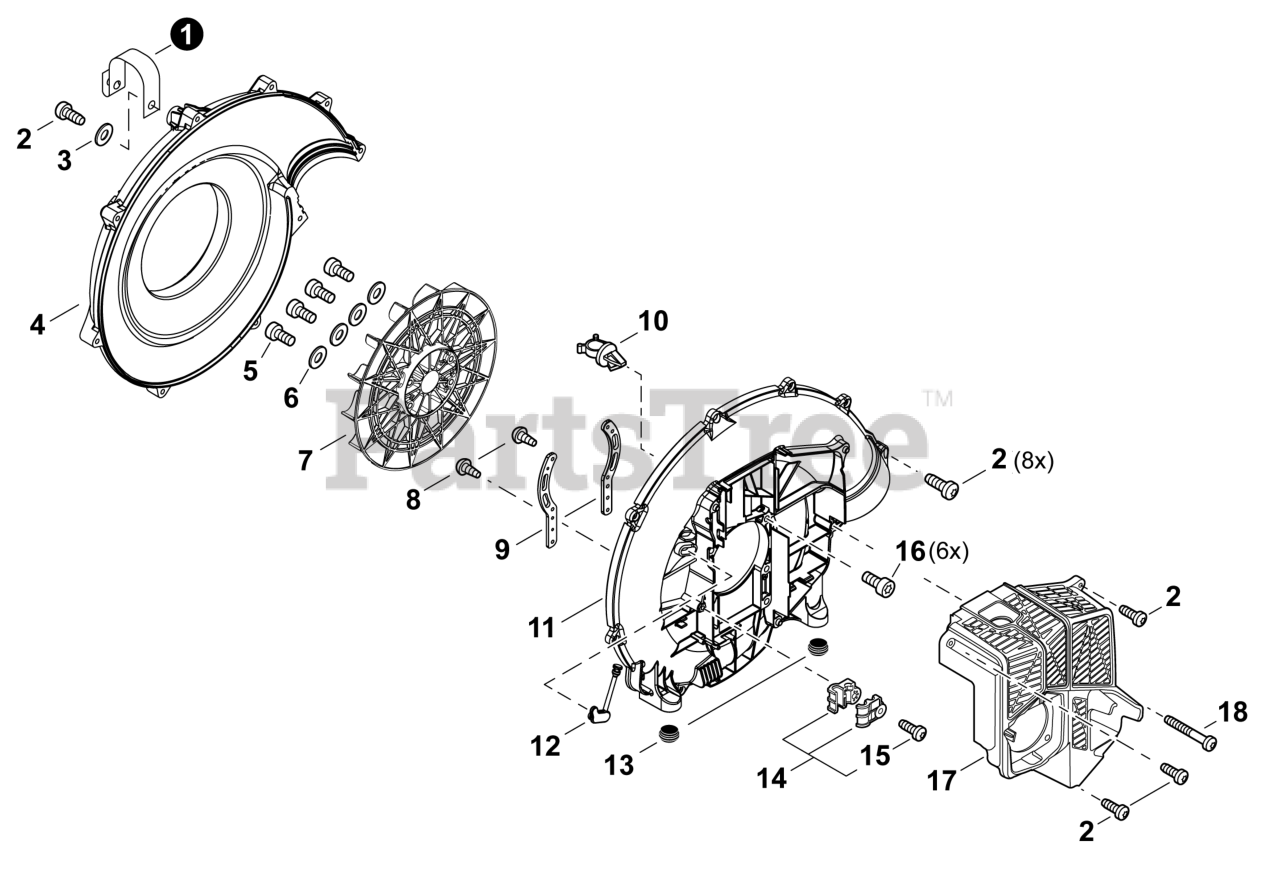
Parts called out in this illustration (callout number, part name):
1	STRAP, SAFETY 1.2x100
2	BOLT, TORX 5x20
3	WASHER 5.5x16x2T
4	COVER, FAN
5	BOLT, TORX 5x30
6	WASHER 5.5x16x2T
7	FAN, BLOWER
8	SCREW TAPPING 3x12
9	BRACKET, ENGINE
10	CLIP, CABLE
11	CASE, FAN
12	GROMMET
13	CUSHION
14	CABLE HOLDER SET
15	BOLT, TORX 5x25
16	BOLT, TORX 5x30
17	COVER, ENGINE
18	BOLT, TORX 5x55
